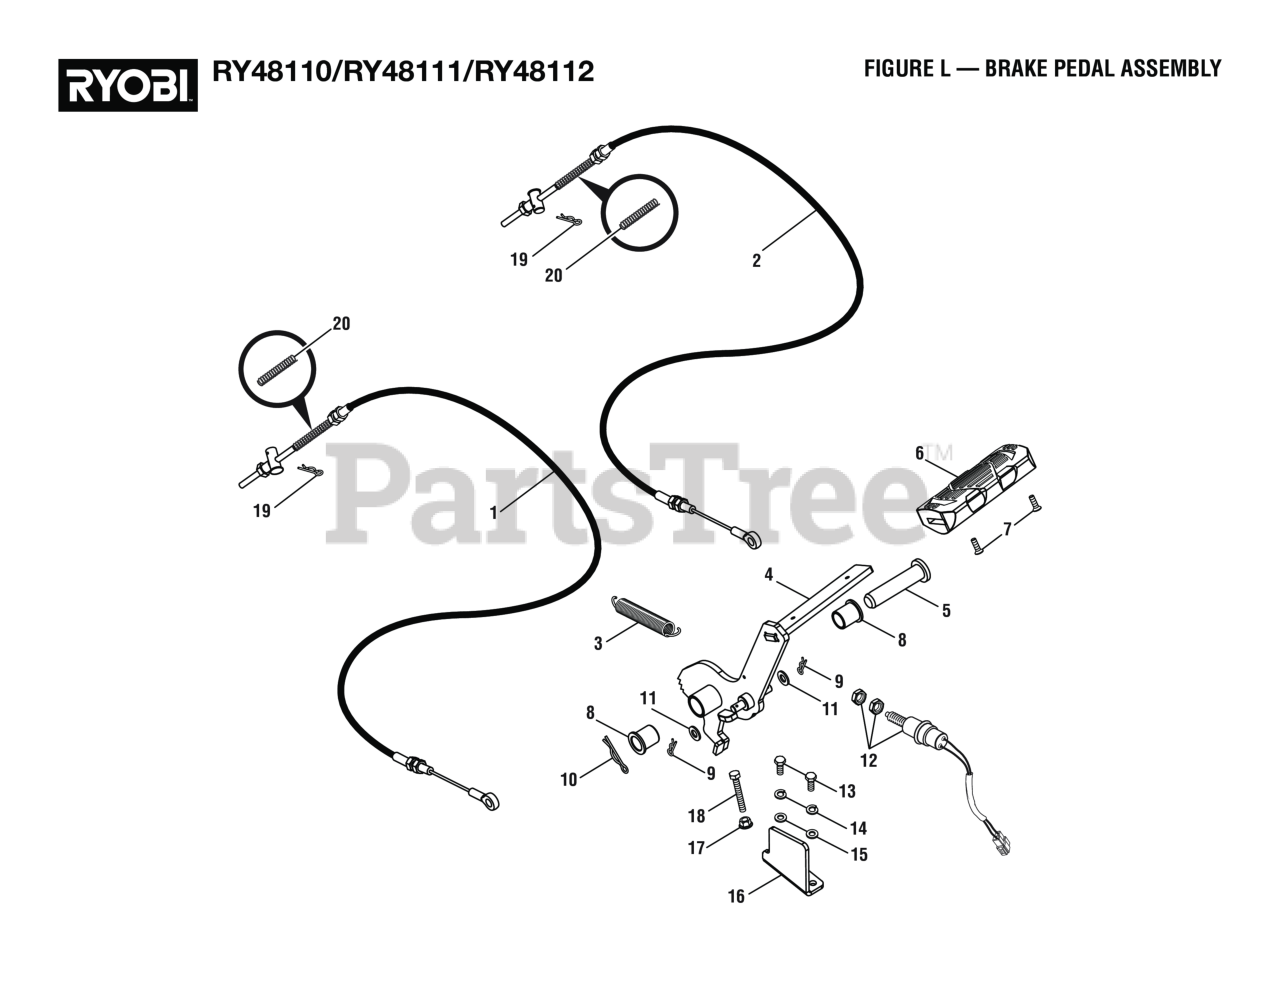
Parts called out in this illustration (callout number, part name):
1	Right Brake Cable
2	Left Brake Cable
3	Pedal Spring
5	Clevis Pin
6	Brake Pedal
7	Screw (M5 x 16 mm, Flat Hd.)
9	Cotter Pin (8 mm)
10	Lock Pin (16 mm)
11	Washer (OD16 x ID8.4 x 1.6t)
12	Brake Switch Assembly
13	Bolt (M6 x 16 mm, Hex Hd.)
14	Spring Washer (M6) (For Deck Motor Controllers T & U)
15	Washer (OD12 x ID6.4 x 1.6t) (For Deck Motor Controllers T & U)
16	Brake Switch Guard
17	Flange Nut (M6)
18	Bolt (M6 x 45 mm, Hex Hd.)
19	Cotter Pin (12 mm)
20	Compression Spring
